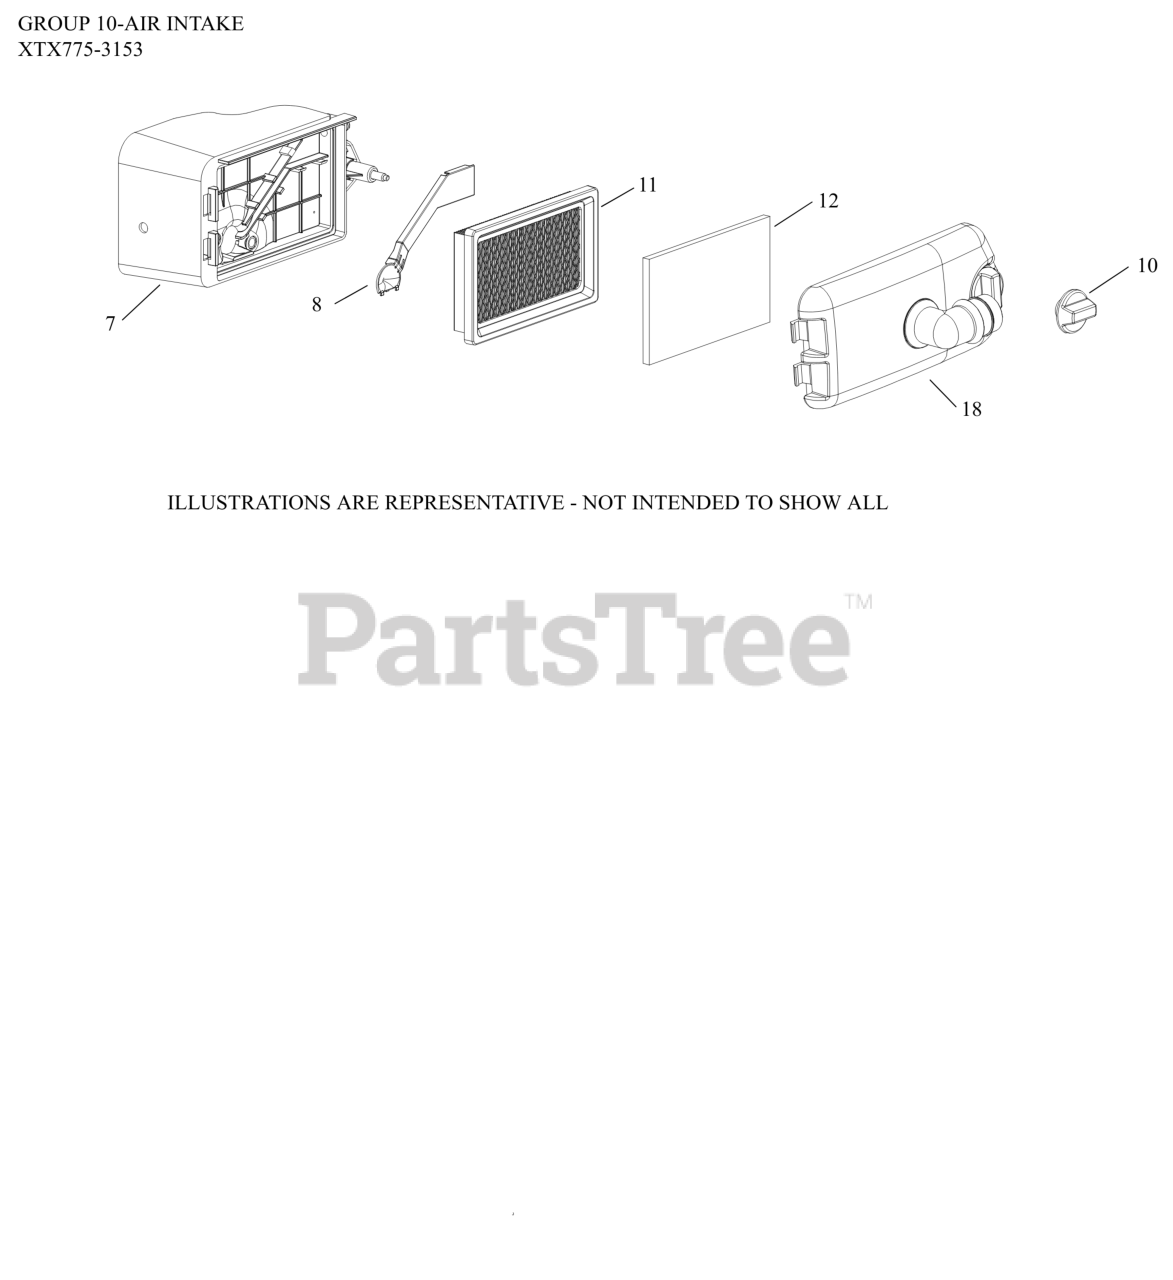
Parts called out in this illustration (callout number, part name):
7	AIR CLEANER BASE-USE 14 094 23-S
8	COVER, A/C BASE (BREATHER GAS)
10	KNOB-USE 14 341 07-S
11	ELEMENT, AIR FILTER
12	ELEMENT, PRE-CLEANER
18	COVER ASSEMBLY, AIR CLEANER (SERVICE)
